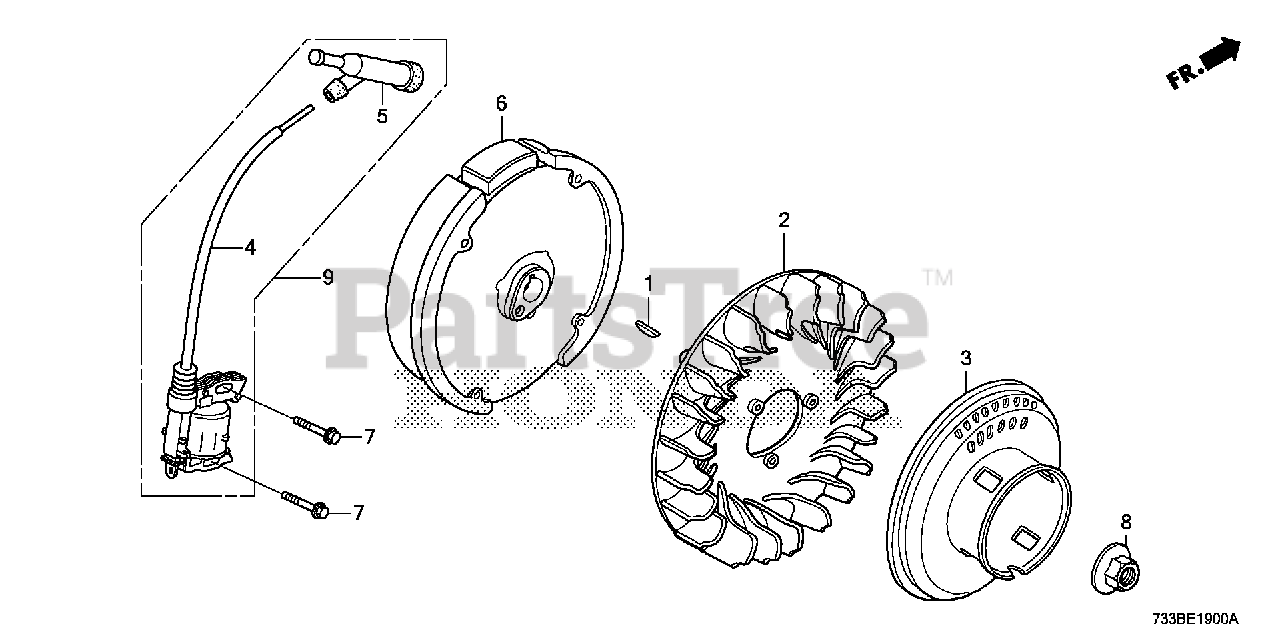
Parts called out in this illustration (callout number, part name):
1	KEY, SPECIAL WOODRUFF (25X18)
2	FAN, COOLING
3	PULLEY, STARTER
4	COIL ASSY., IGNITION (KOKUSAN)
5	CAP ASSY., NOISE SUPPRESSOR (TEC)
5	CAP ASSY., NOISE SUPPRESSOR (KOKUSAN)
6	FLYWHEEL (YUXIN)
7	BOLT, FLANGE (6X25) (CT200)
8	NUT, SPECIAL (14MM)
9	COIL ASSY., IGNITION (TEC)
